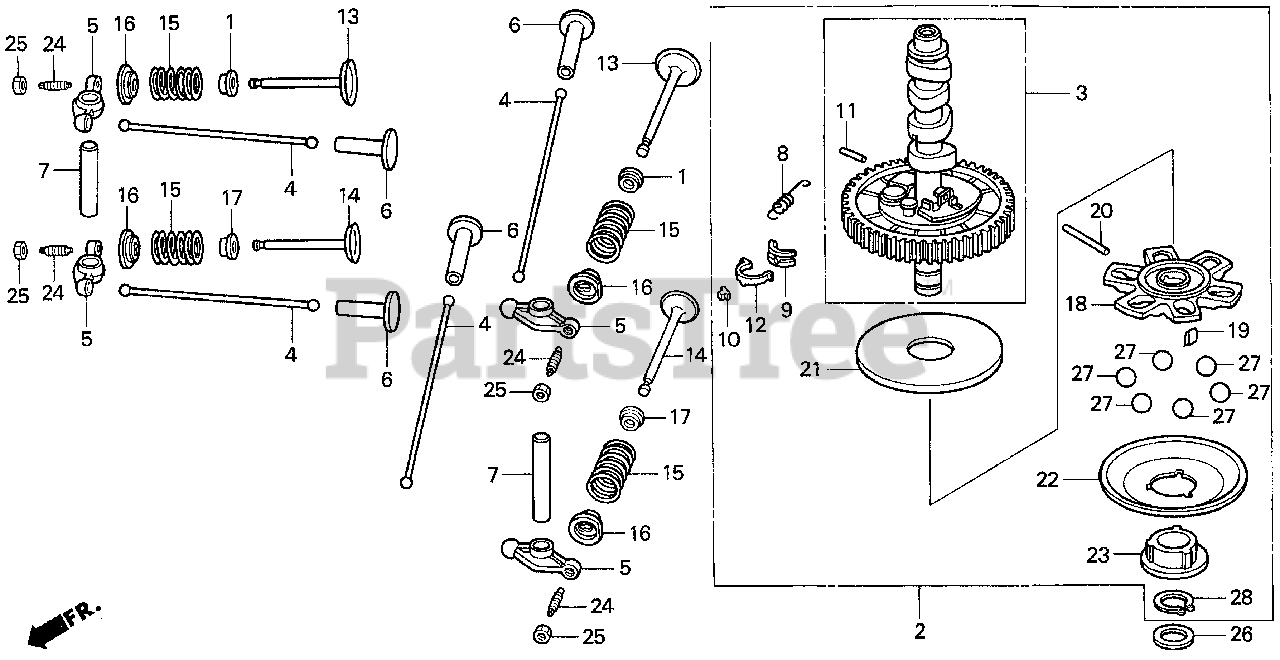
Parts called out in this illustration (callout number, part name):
1	SEAL, VALVE STEM
2	CAMSHAFT ASSY.
3	CAMSHAFT
4	ROD, PUSH
5	ARM, VALVE ROCKER
6	LIFTER, VALVE
7	SHAFT, ROCKER ARM
8	SPRING, WEIGHT RETURN
9	HOLDER, DECOMPRESSION PIN
10	PIN A, DECOMPRESSION
10	PIN B, DECOMPRESSION
10	PIN C, DECOMPRESSION
10	PIN D, DECOMPRESSION
10	PIN E, DECOMPRESSION
10	PIN C, DECOMPRESSION (8.05)
10	PIN D, DECOMPRESSION (8.15)
10	PIN E, DECOMPRESSION (8.25)
11	ROD, DECOMPRESSION
12	SPRING, DECOMPRESSION PIN HOLDER
13	VALVE, IN.
14	VALVE, EX.
15	SPRING, VALVE
16	RETAINER, IN. VALVE SPRING
17	SEAT, VALVE SPRING
18	HOLDER, GOVERNOR WEIGHT
19	PLATE, GOVERNER WEIGHT HOLDER
20	PIN, GOVERNOR WEIGHT HOLDER
21	PLATE, GOVERNOR (LOWER)
22	PLATE, GOVERNOR SLIDER
23	SLIDER, GOVERNOR
24	SCREW, TAPPET ADJ.
25	NUT, TAPPET ADJ.
26	WASHER, THRUST (17.2MM)
27	BALL, STEEL (18)
28	CIRCLIP (OUTER) (17MM)
